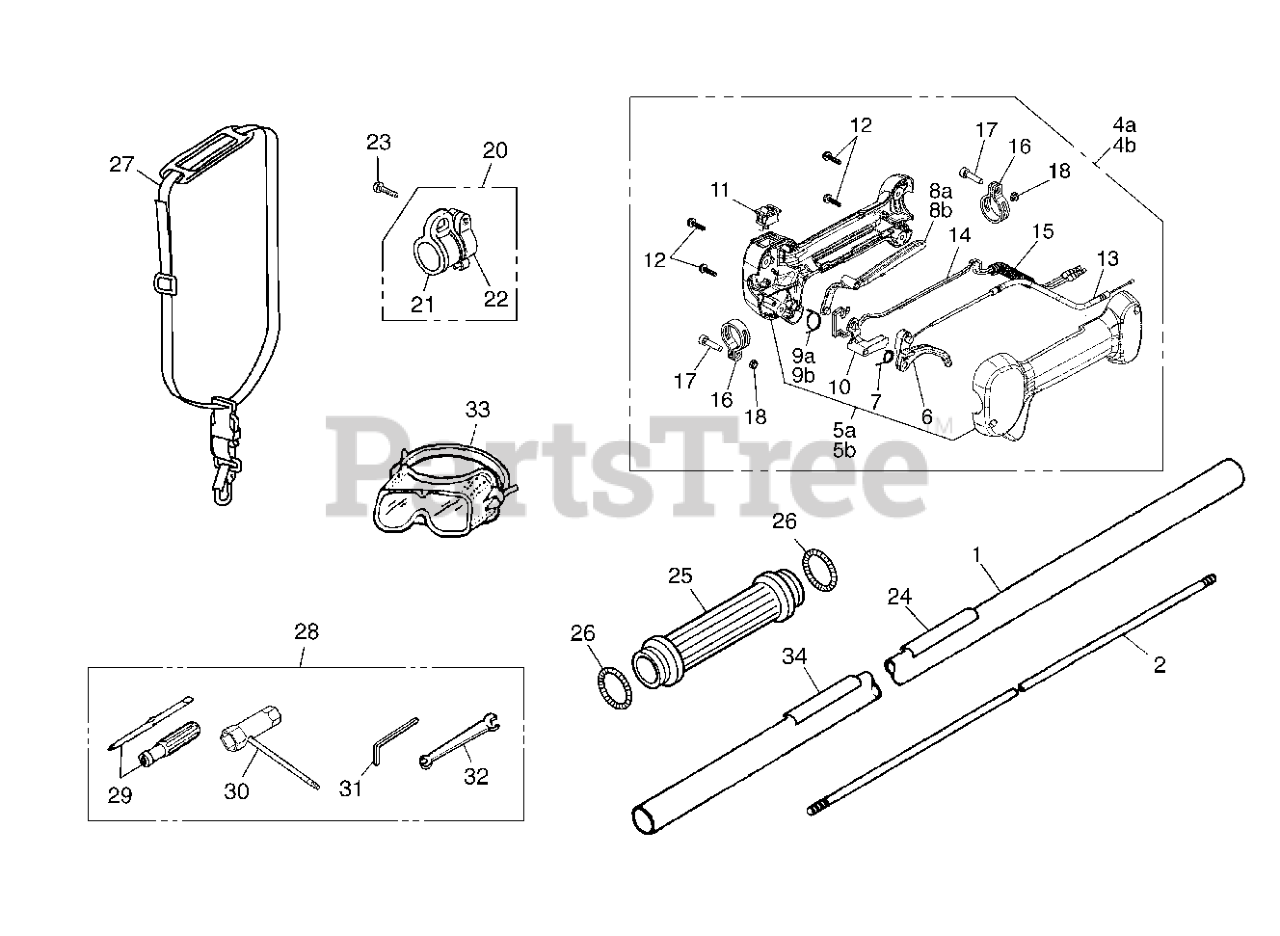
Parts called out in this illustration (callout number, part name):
1	PIPE COMP
4	GRIP ASSY
5	GRIP HALF SET
6	LEVER, THROTTLE
7	SPRING, THROTTLE
8	LEVER FOR GRIP (RPLS -0600)
8	LEVER, SAFETY
9	SPRING JOINT
9	SPRING
10	LEVER JOINT
14	CORD - C
18	NUT
20	HANGER COMP.
21	HANGER
24	NAME PLATE PSZ460S & SGZ24060S
27	STRAP ASSY
28	TOOL-SET
33	GOGGLExxx (RPLS
34	LABEL CAUTON FOR BC
